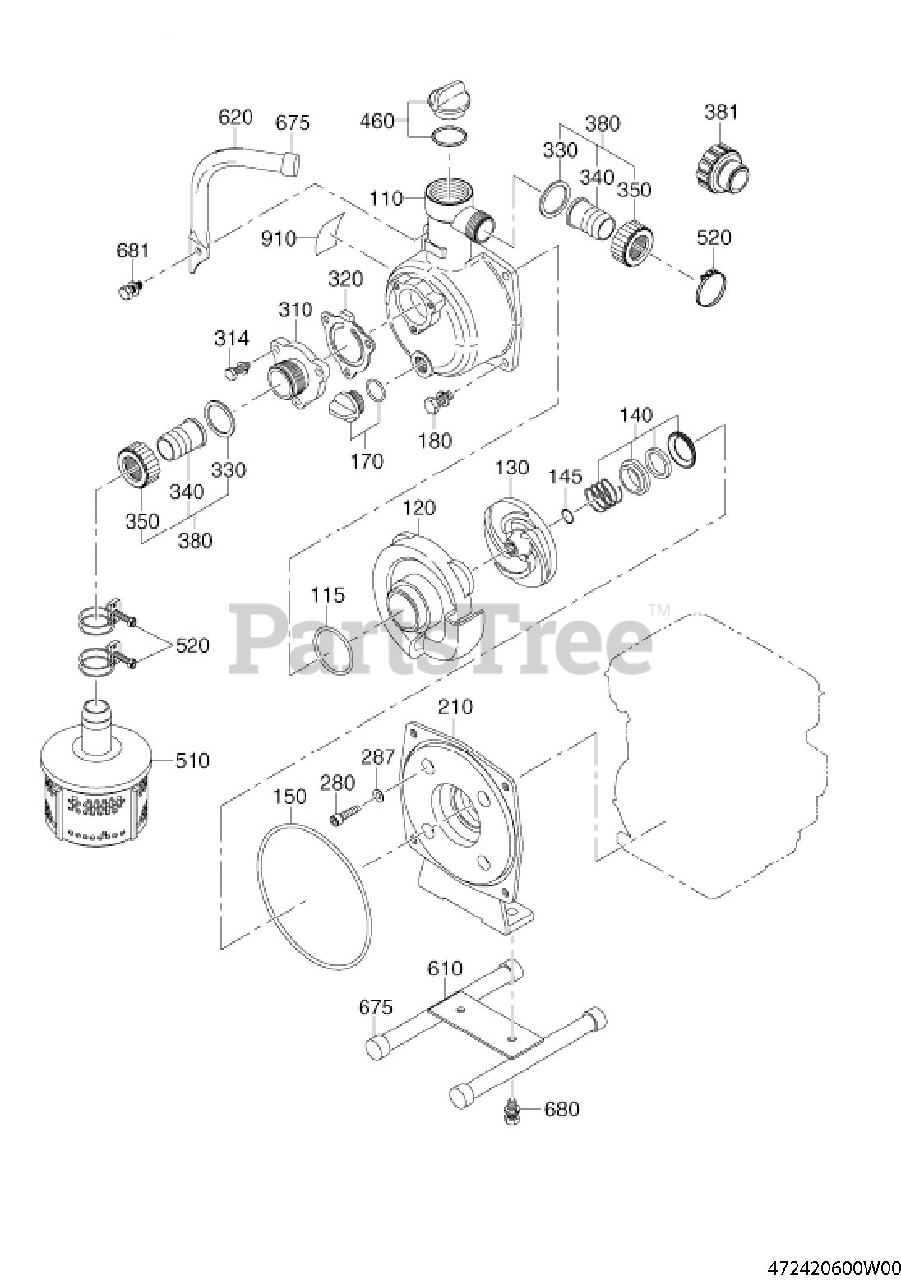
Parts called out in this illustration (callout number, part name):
140	MECHANICAL SEAL
145	ADJUSTING WASHER
150	O RING
180	BOLT & WASHER AY
280	SOCKET HEAD BOLT
310	SUCTION FLANGE
314	BOLT & WASHER AY
330	PACKING(COUPLING)
340	NIPPLE
350	PACKING, COUPLING
381	GARDEN HOSE ADAPTER
680	BOLT & WASHER AY
681	BOLT & WASHER AY
910	LABEL(PUMP NAME)
